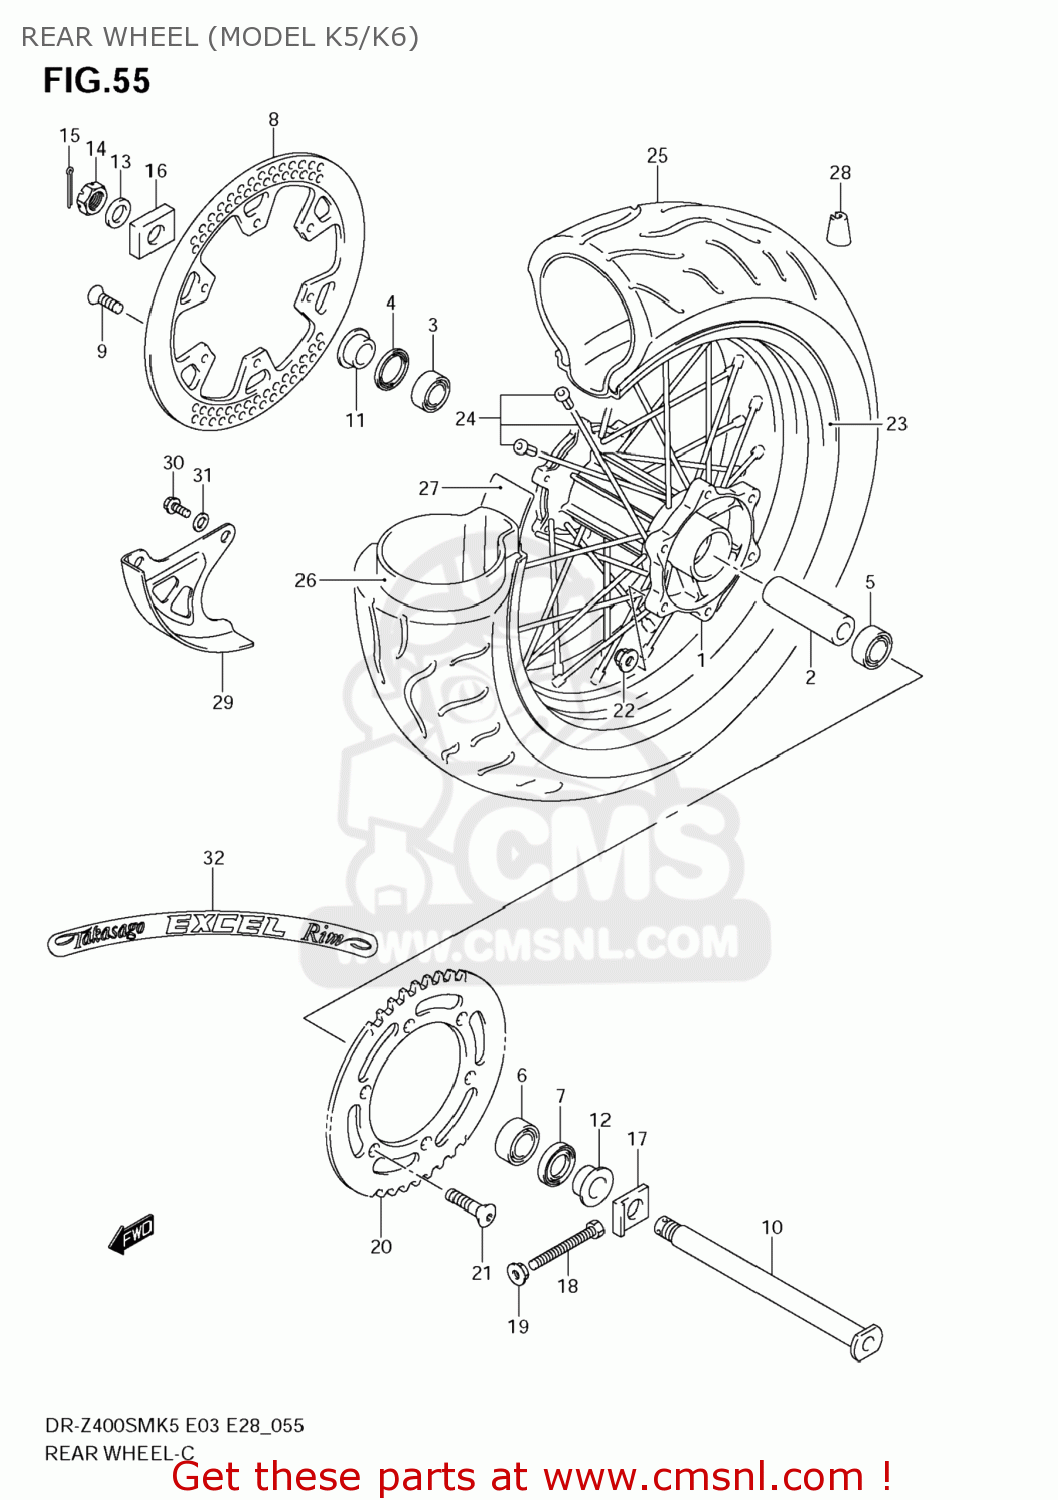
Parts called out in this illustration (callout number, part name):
1	HUB,RR WHEEL
2	SPACER,RR HUB BEARING
3	BEARING
4	SEAL(29X42X6)
5	BEARING
6	BEARING
7	SEAL,OIL(29X47X6)
8	DISC,RR BRAKE
9	SCREW(6X18)
10	AXLE,RR
11	SPACER,RR AXLE
12	SPACER,RR AXLE
13	WASHER(19X32X3.2)
14	NUT
15	PIN
16	ADJUSTER,CHAIN,R
17	ADJUSTER,CHAIN,L
18	BOLT(8X50)
19	NUT
20	SPROCKET,RR(NT:41)
21	BOLT(8X30.5)
22	NUT
23	RIM,RR WHEEL(17XMT4.50 AL)(BLK
24	SPOKE SET,RR WHEEL
25	TIRE,RR(140/70R17M/C 66H)
26	TUBE ASSY,WHEEL INNER
27	PROTECTOR,WHL INR TUBE
28	BALANCER,WHEEL(20G)
29	COVER,REAR DIS
30	BOLT(6X10)
31	WASHER
32	EMBLEM,EXCEL(8 PIECES SET)
